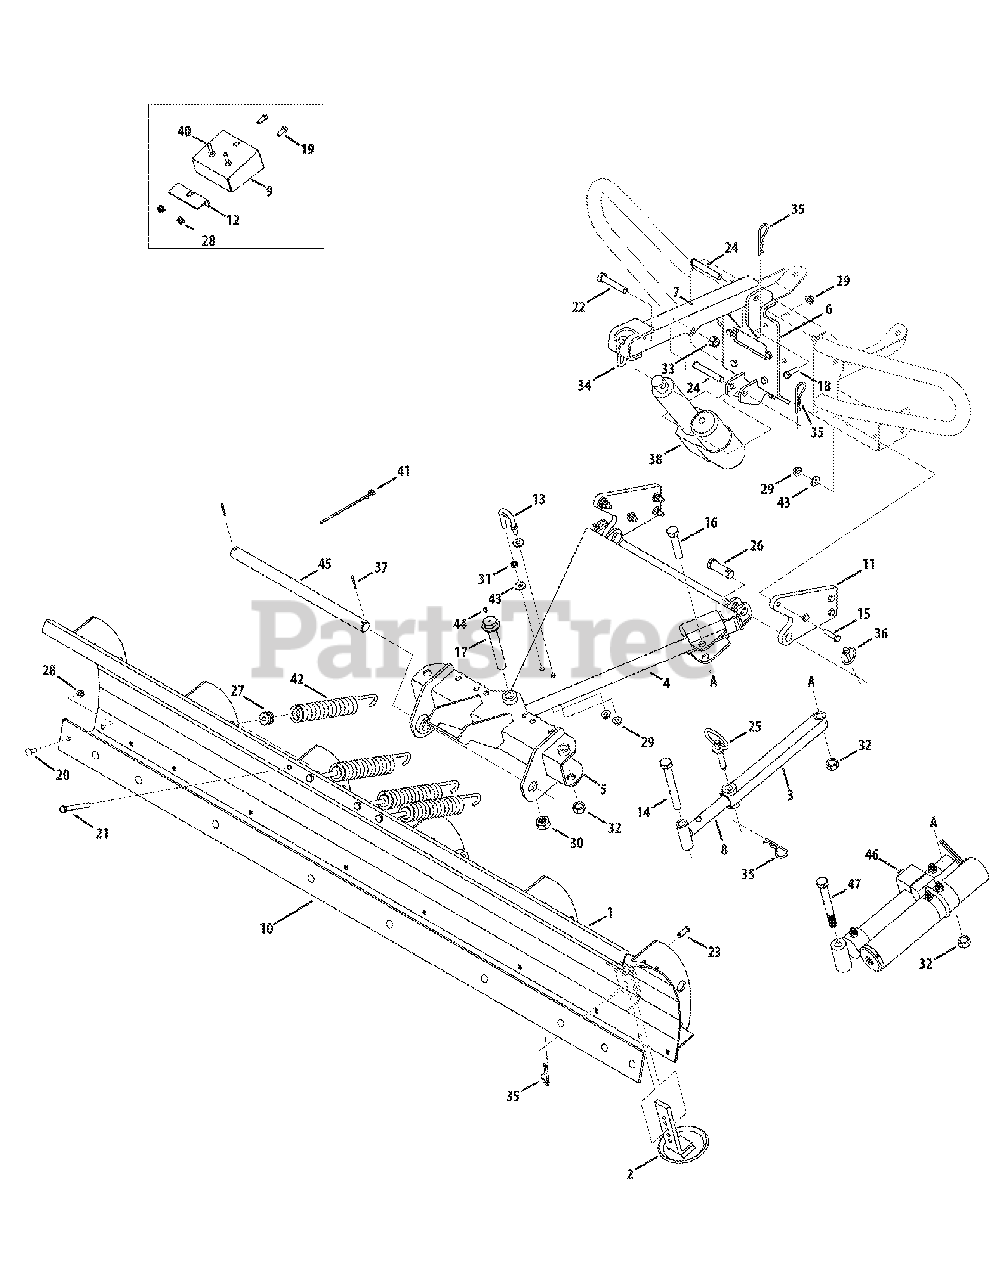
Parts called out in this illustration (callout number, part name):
1	Blade Assembly, 72"
3	Adjustable Arm Assembly
5	Snow Blade Mounting Assembly
7	Plow Lift Arm Assembly
8	Blade Adjustment Arm Assembly
10	Blade Scraper, 72"
13	U-Bolt, 3/8-16
14	Hex Head Screw, 5/8-18 x 5.50
15	Hex Head Screw, 3/8-16 x 1.50
16	Hex Head Screw, 5/8-18 x 3.00
17	Spindle Bolt, 3/4-16 x 5.37
18	Hex Head Screw, 3/8-16 x 1.25
19	Hex Head Screw, 5/16-18 x .75
20	Carriage Bolt, 5/16-18 x .875
21	Hex Head Screw, 3/8-16 x 3.50
22	Hex Head Screw, 1/2-13 x 2.75
23	Clevis Pin, .375 dia. x .969
24	Clevis Pin, .50 x 3.25
25	Hitch Pin, .50 x 2.5
26	Clevis Pin, .750 Od. x 2.00 Lg.
27	Insert Spring
28	Flange Lock Nut, 5/16-18
29	Flange Lock Nut, 3/8-16
30	Hex Lock Nut, 3/4-16
31	Jam Nut, 3/8-16
32	Hex Lock Nut, 5/8-18
33	Hex Lock Nut, 1/2-13
34	Plow Lift Chain, No. 30
35	Internal Cotter Pin
37	Cotter Pin
38	Plow Lift Actuator
40	On-Off-On Toggle Switch
41	Cable Tie
42	Adjustable Blade Spring
43	Flat Washer, .38 x .93 x .110
44	Grease Fitting, 1/4-28
45	Blade Pivot Rod
46	Angle Actuator Complete
47	Hex Head Screw, 5/8-18.5 x 5.25
